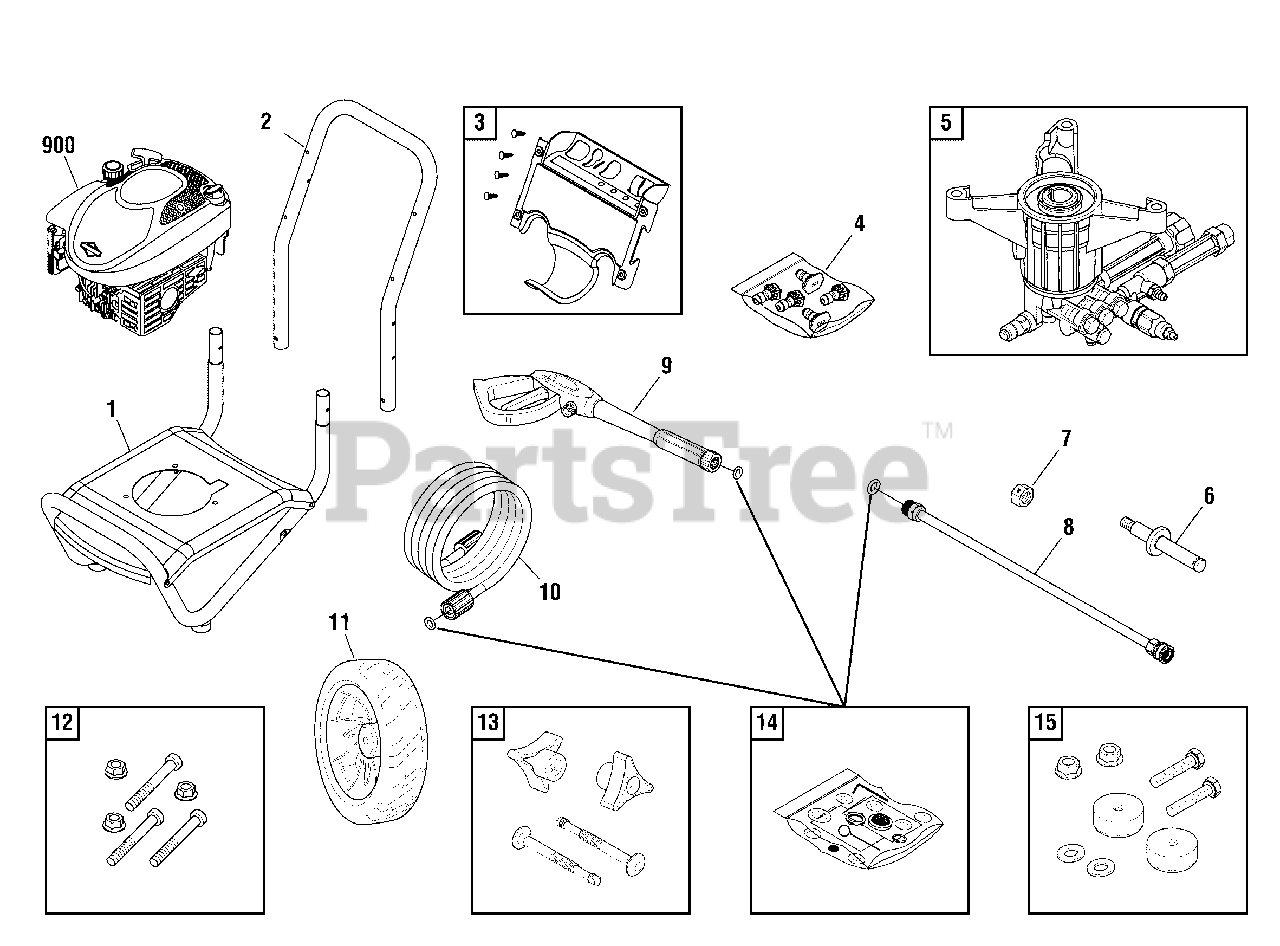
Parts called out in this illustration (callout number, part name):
4	KIT-QC NOZZLES
8	EXTENSION-QC
9	GUN
10	HOSE
12	KIT-HARDWARE, PUMP MOUNTING
13	KIT-HARDWARE HANDLE
15	MOUNT-VIBRATION
900	** ENGINE
